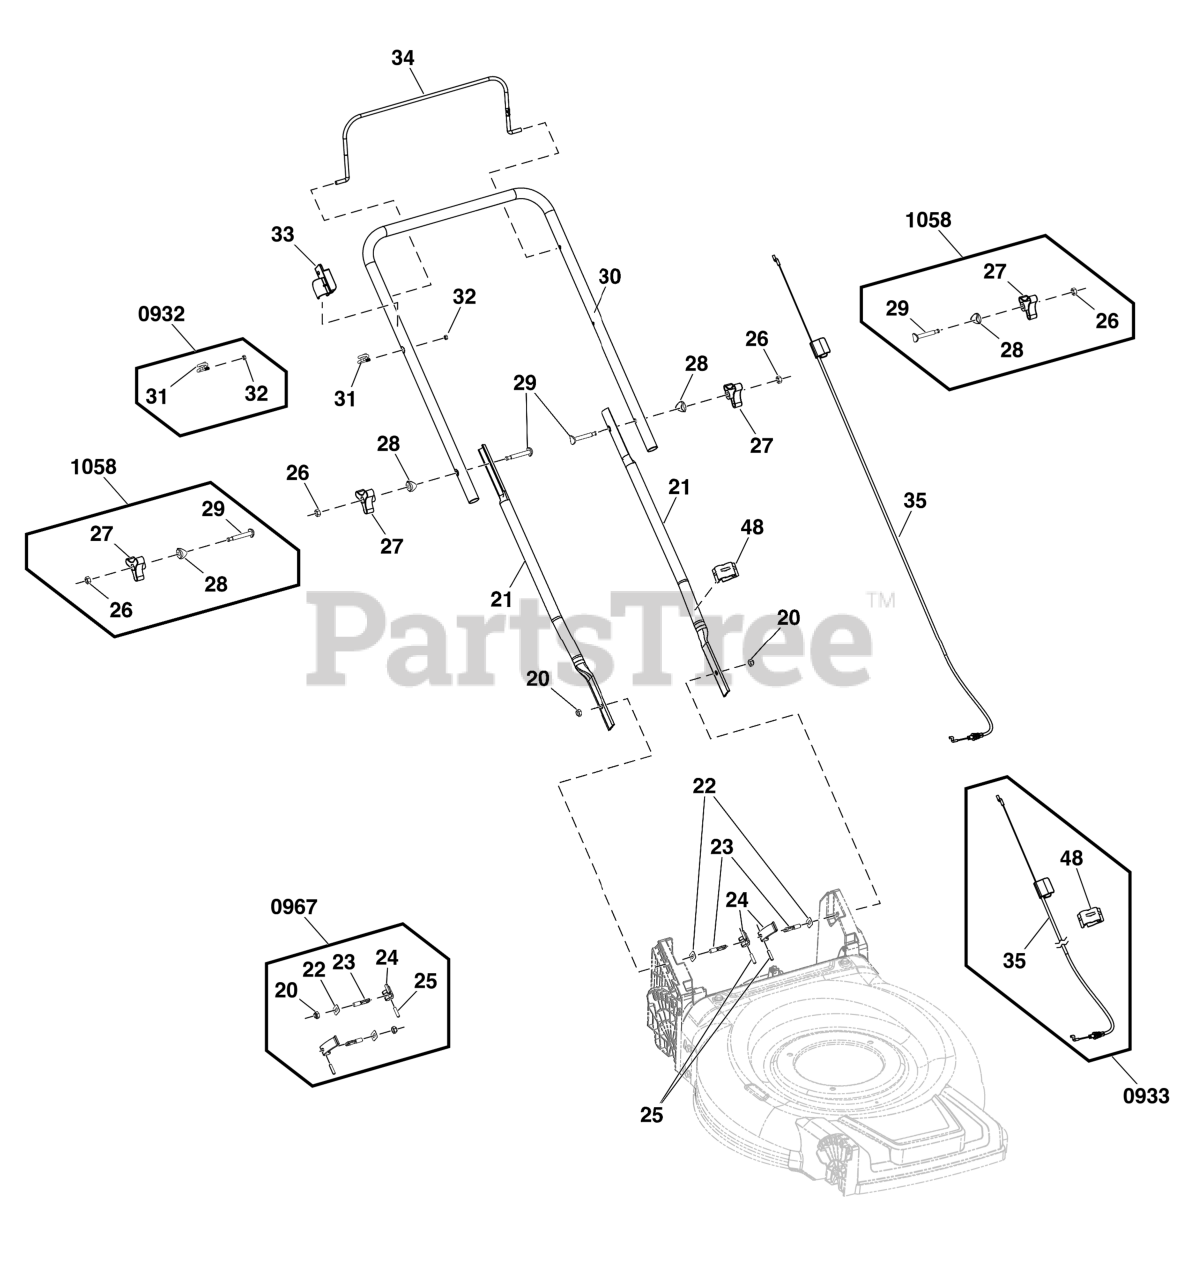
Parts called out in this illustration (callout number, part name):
20	NUT, Lock
21	HANDLE, Lower
22	PLATE, Compression
23	BOLT, Locking Handle
24	CAM, Handle
25	PIN
26	NUT
27	KNOB, Wing
28	WASHER, Curved
29	BOLT, Carriage
30	HANDLE, Upper
31	GUIDE, Rope
32	NUT, Lock
33	BRACKET, Rod
34	BAIL ASSEMBLY
35	CABLE, Engine Stop
48	CLIP, Cable
0932	KIT, Rope Guide
0933	KIT, Cable, Engine Stop
0967	KIT, Knob, Lever
1058	KIT, Wing Knob, Handle
